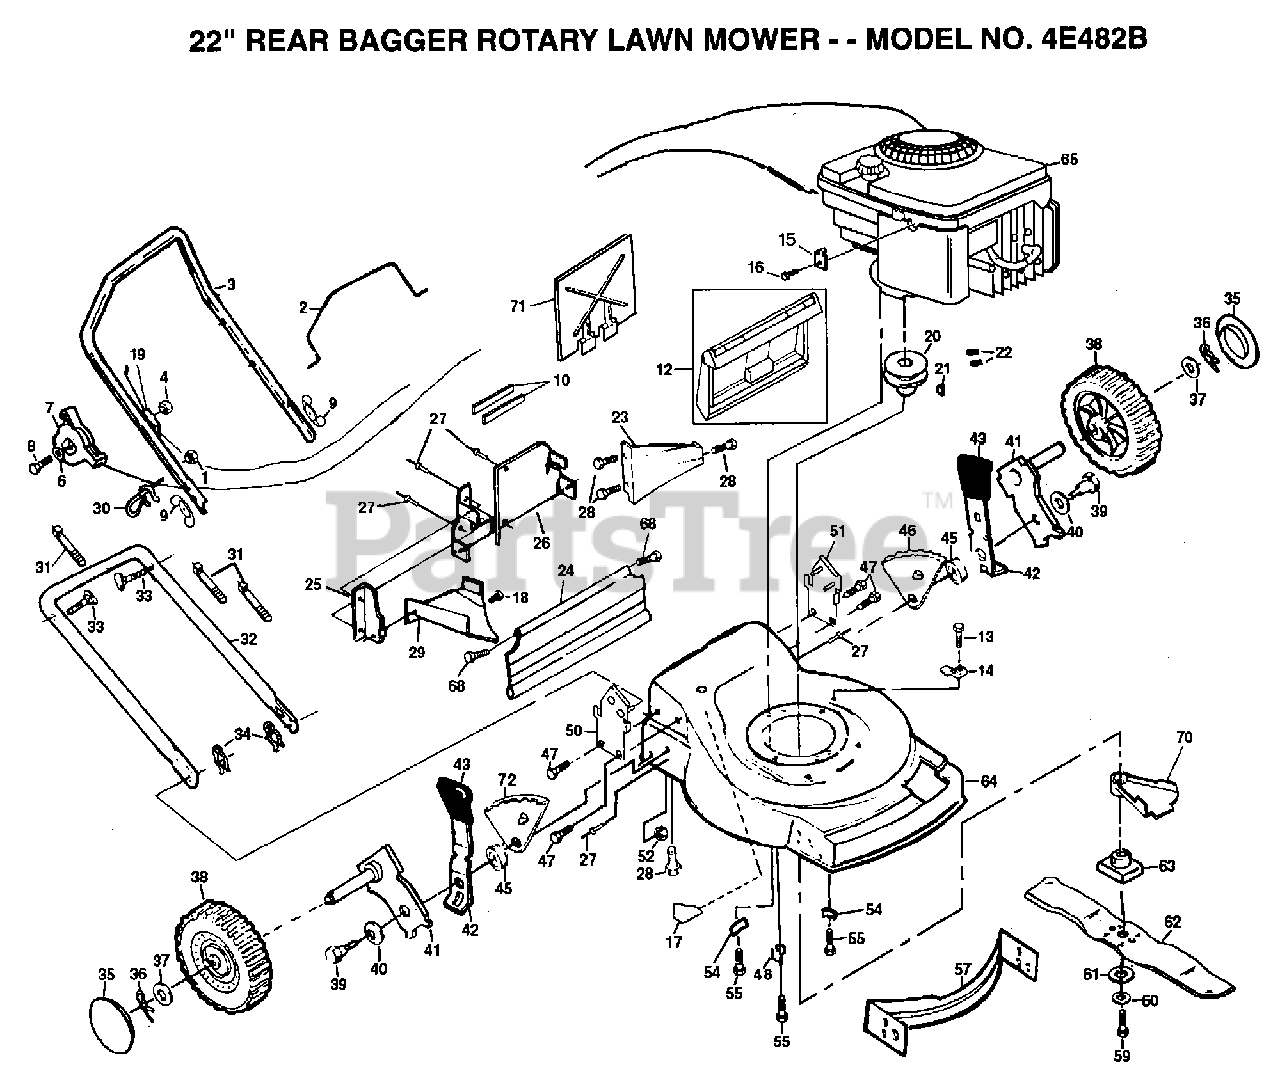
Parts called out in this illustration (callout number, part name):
1	NUT
2	"BAR,CONT"
6	WASHER PM
7	CNTL.THROT.47.5
9	"NUT,WING PM"
10	"SEAL,REAR DOOR"
13	TAPPING SCREW
14	GUIDE CLIP PM
15	CABLE CLAMP
17	DECAL HYT
18	SCREW PM
19	"CABLE,ENG ZONE CO"
20	ENGINE.PULLEY.FWG
21	HI PRO KEY PM
22	SCREW
23	REAR BAFFLE
26	PLATE.BACK.22RD
27	BLIND RIVET
28	SCREW
29	DISCHARGE BAFFLE
30	ROPE GUIDE
33	BOLT.HANDLE.LM
34	HAIRPIN COTTER
35	HUB CAP
36	RETAINER CLIP PM
37	WASHER
40	"WASHER, BELLEVIL."
41	AXLE ARM
42	SPRING SELECTOR
43	KNOB PM
47	SCREW
48	DEBRIS SHLD RET
52	LOCKNUT PM
55	SCREW
59	SCREW
60	LOCKWASHER
61	"WASHER,HARDEN"
63	ADAPTOR.BLADE.LM
64	KIT.HSG.22RD.FWGD
68	HINGE SCREW
71	MULCHER PLATE
